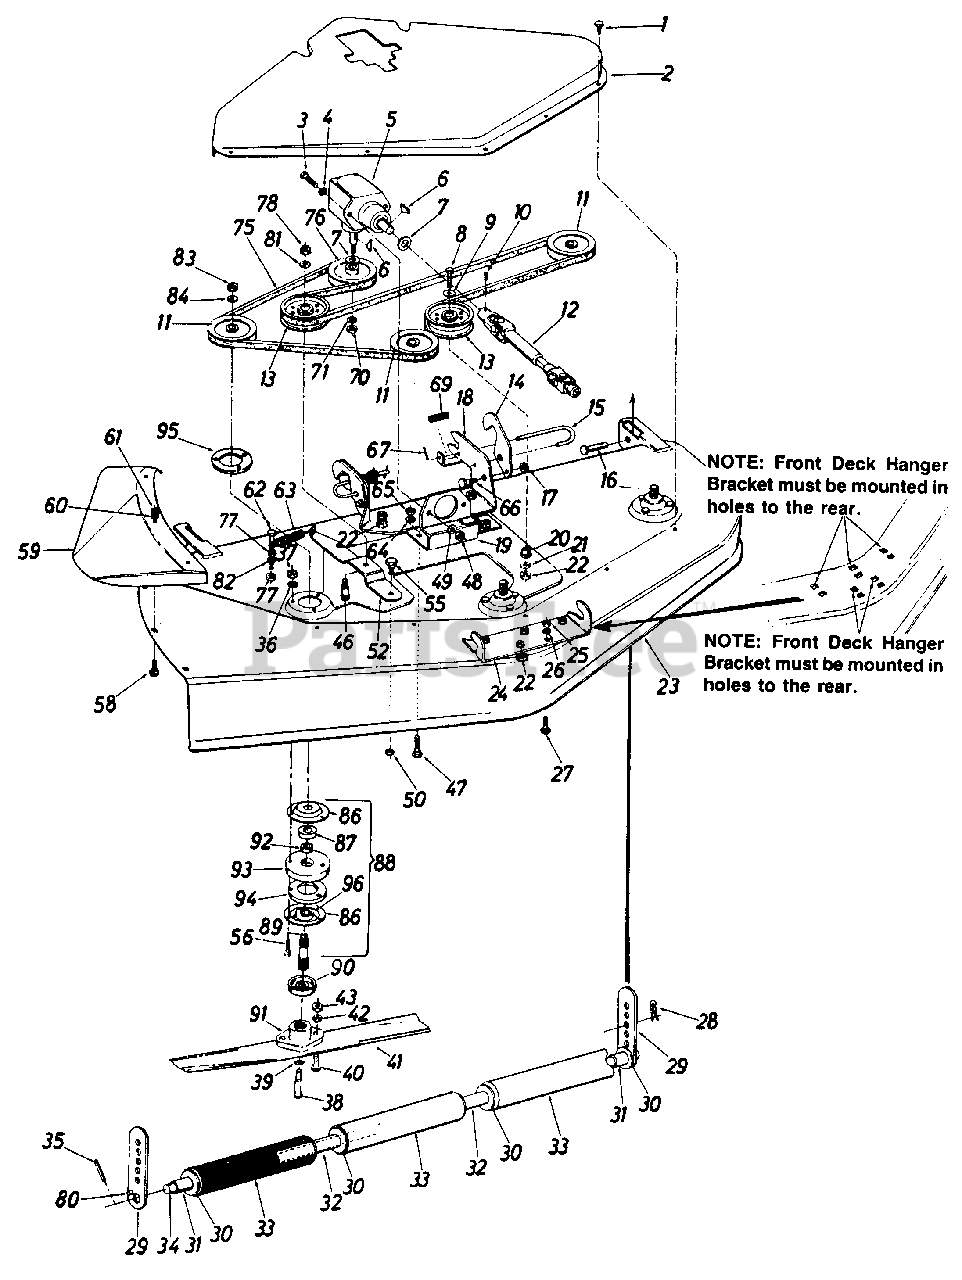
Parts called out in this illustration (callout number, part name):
1	Hex B-Tap Scr. 1/4-20 x .38" Lg.
4	Ext. L-Wash. 3/8" I.D.
5	Right Angle Drive
6	#9 Hi-Pro Key 3/16 x 3/4" Dia.
7	Fl-Wash. 29/32" I.D.
8	Hex Bolt 3/8-16 x 2.25" Lg.
9	Fl-Wash. 3/8" I.D.
10	Sq. Hd. Set Scr. 3/8-16 x .50"
11	Deck Pulley
12	Unlversal Drive Shaft Ass'y.
13	Deck Idler Pulley
14	Hanger Lock
15	Release Pin
16	Clevis Pin .50" Dia.
17	Hex L-Nut 5/16-18 Thd.
21	L-Wash. 3/8" I.D.
22	Hex Nut 3/8-16 Thd.
26	L-Wash. 5/16" I.D.
27	Carriage Bolt 5/16-18 x 1" Lg.
28	Internal Cotter Pin
30	Fl-Wash. .75" I.D. x 1.5" O.D.
31	Spacer .758" I.D. x 1.25" O.D. x .530
34	Roller Shaft
35	Roll Pin 3/16 x 1.25"
36	L-Wash. 5/16" I.D.
37	Hex Cent. L-Nut 5/16-24 Thd.
38	Hex Self-Tap Scr. 3/8-24 x 75" Lg.
39	L-Wash. 3/8" I.D. H.D.
40	Hex Bolt 5/16-24 x 1" Lg.
41	Blade 17"
42	L-Wash. 5/16" I.D.
43	Hex L-Nut 5/16-24 Thd.
46	Hex Bolt 5/8-18 x 1.31" Lg.
47	Carriage Bolt 5/16-18 x .75"
48	Hex Nut 3/8-16 Thd.
49	L-Wash. 3/8" I.D.
50	Hex L-Nut 7/16-14 Thd.
56	Hex Bolt 5/16-24 x 1.5" Lg. (Grade 5)
58	Carriage Bolt 5/16-18 x .75" Lg.'
60	L-Wash. 5/16" I.D.
61	Hex Nut 5/16-18 Thd.
62	Hex Bolt 1/4-28 x 1-3/4" Lg.
63	Extension Spring
64	L-Wash. 5/16" I.D.
65	Hex Nut 5/16-18 Thd.
66	Shld. Bolt
67	Roll Pin 1/8" Dia.
69	Compression Spring
70	Hex L-Nut 5/8-18 Thd.
71	L-Wash. 5/8" I.D.
75	"V"-Belt
76	Drive Pulley
77	Hex L-Nut 1/4-28 Thd.
78	Hex Cent. L-Jam Nut 5/8-18 Thd.
80	Spring Pin Spiral 1/4" Dia. 1.00" Lg.
81	Fl-Wash..62" I.D.
82	L-Wash. 1/4" I.D.
83	Hex .Jam Nut 5/8-18 Thd.
84	L-Wash. 5/8" I.D.
86	Bearing Housing
87	Ball Bearing
88	Deck Spindle Ass'y.
89	Spindle
90	Bearing Shield
91	Blade Adapter
92	Spacer
93	Spindle Spacer Plate
94	Reinforcement Plate
95	Spindle Reinforcement Plate
96	Open Bearing Housing
